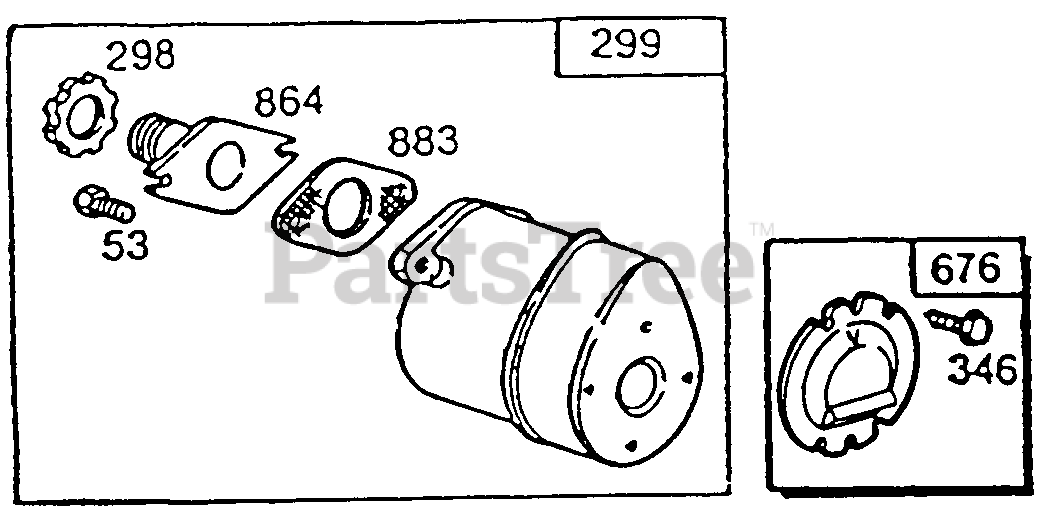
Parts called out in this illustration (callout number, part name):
53	Screw-Exhaust
298	Lock Nut-Muffler
299	Muffler-Exhaust
346	Screw-Sem
676	Deflector-Muffler
864	Adapter Ass'y.-Muffler
883	Gasket-Muffler
